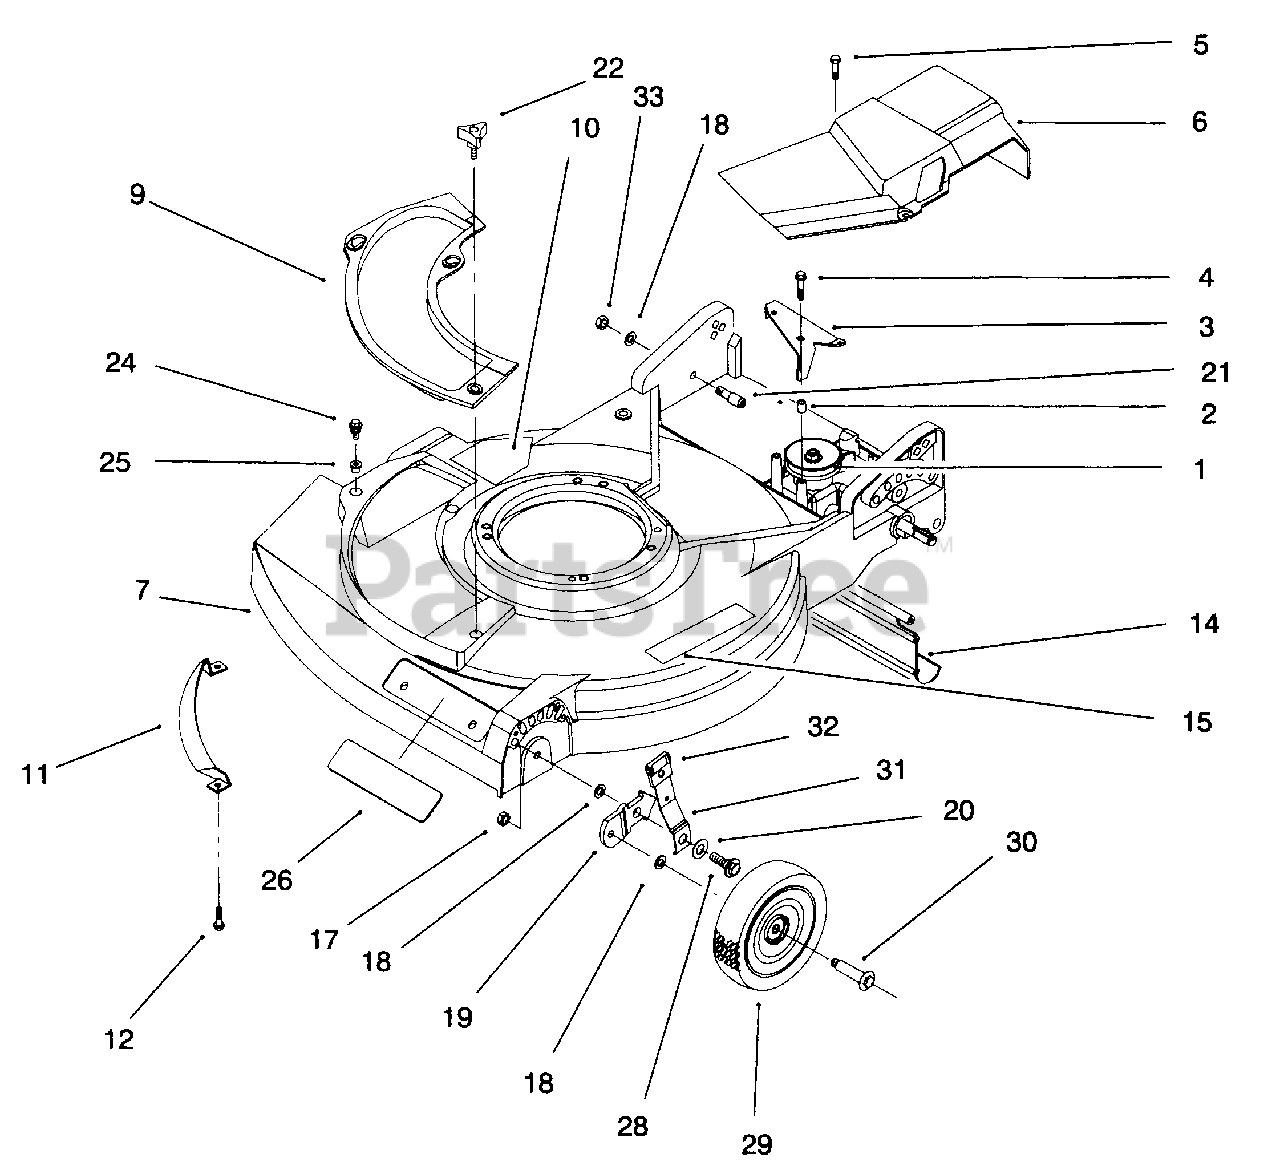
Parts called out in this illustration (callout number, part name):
1	Gear Case Assembly
2	Bushing-Spacer
3	Bracket-Actuator
4	Screw
5	Screw-Thr'd Form
6	Cover-Drive
7	Housing (Incl. Ref. #10, 15, & 26)
9	Plate-Cover
10	Decal-Danger
11	Toe Bar
12	Screw-Hex Washer Hd.
14	Shield-Trailing
15	Decal-Warning
17	Nut-Lock
19	Bracket-Wheel Height Adj.
20	Washer-Belleville
21	Bolt-Shoulder
22	Knob-Cover Plate
24	Screw-Sems Thr'd Form
26	Decal-Deck
28	Bolt-Shoulder
29	Wheel & Tire Assembly-6"
30	Bolt-Wheel
31	Spring Arm Ass'y-Front
32	Knob-Height Adjust
33	Nut-Lock
